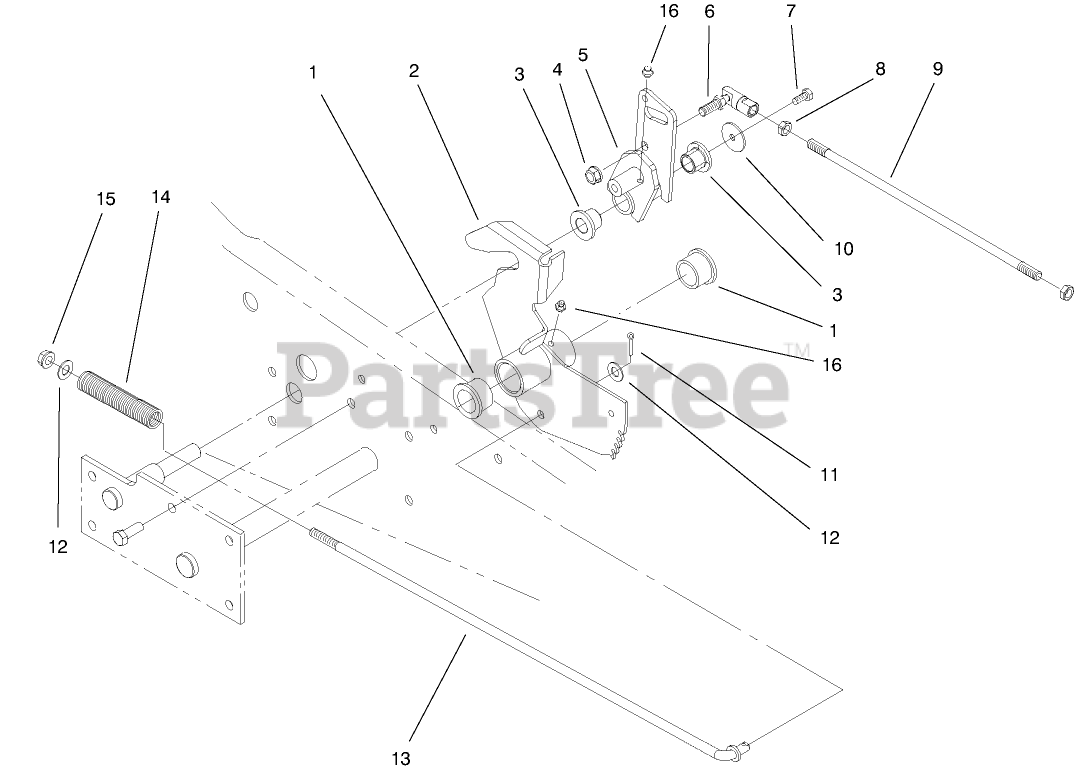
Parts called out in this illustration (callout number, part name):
1	BUSHING-FLANGED
2	PLATE-PIVOT, BRAKE
3	BUSHING
4	NUT-LOCK
5	PIVOT-HYDRO
6	END-TIE ROD, LH
7	SCREW-HH
8	NUT-HEX JAM, LH
9	ROD-PIVOT TO PEDAL
10	WASHER-FLAT
11	PIN-COTTER
12	WASHER-FLAT
13	ROD-BRAKE
14	SPRING-COMPRESSION
15	NUT-LOCK, NI
16	FITTING-GREASE
